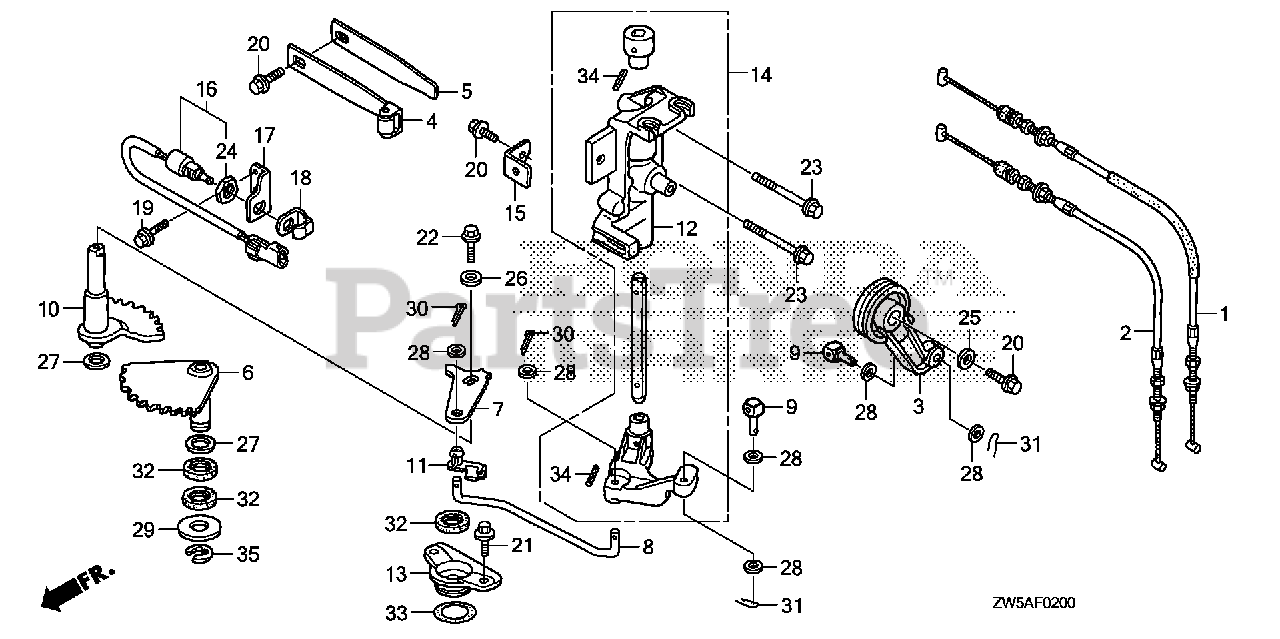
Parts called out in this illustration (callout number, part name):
1	CABLE A, THROTTLE
2	CABLE B, THROTTLE
3	ARM, THROTTLE
4	SPRING, CLICK
5	SPRING, CLICK ASSIST
6	SHAFT, SHIFT (A)
7	ARM, SHIFT
9	PIVOT, SHIFT
10	SHAFT, SHIFT (B)
11	BUSH, SHAFT
12	BRACKET, SHIFT LINK
13	HOLDER, SEAL
14	LINK, SHIFT
15	BRACKET, CLIP (D)
16	SWITCH ASSY., NEUTRAL
17	BRACKET, NEUTRAL SWITCH
18	PLATE, NEUTRAL SWITCH
19	BOLT, FLANGE (6X14) (CT200)
20	BOLT, FLANGE (6X12) (CT200)
21	BOLT, FLANGE (6X11)
22	BOLT, FLANGE (6X12)
23	BOLT, FLANGE (6X42)
24	NUT, HEX. (20MM)
25	WASHER, PLAIN (6MM)
26	WASHER (6MM)
27	WASHER, SHIFT SHAFT
28	WASHER, PLAIN (6MM)
30	PIN, SPLIT (2.0)
31	PIN, LOCK SPECIAL (6MM)
32	OIL SEAL (14X26X6)
33	O-RING (26.9X2.4) (NOK)
34	PIN, SPRING (3X18)
35	E-RING (12MM)
